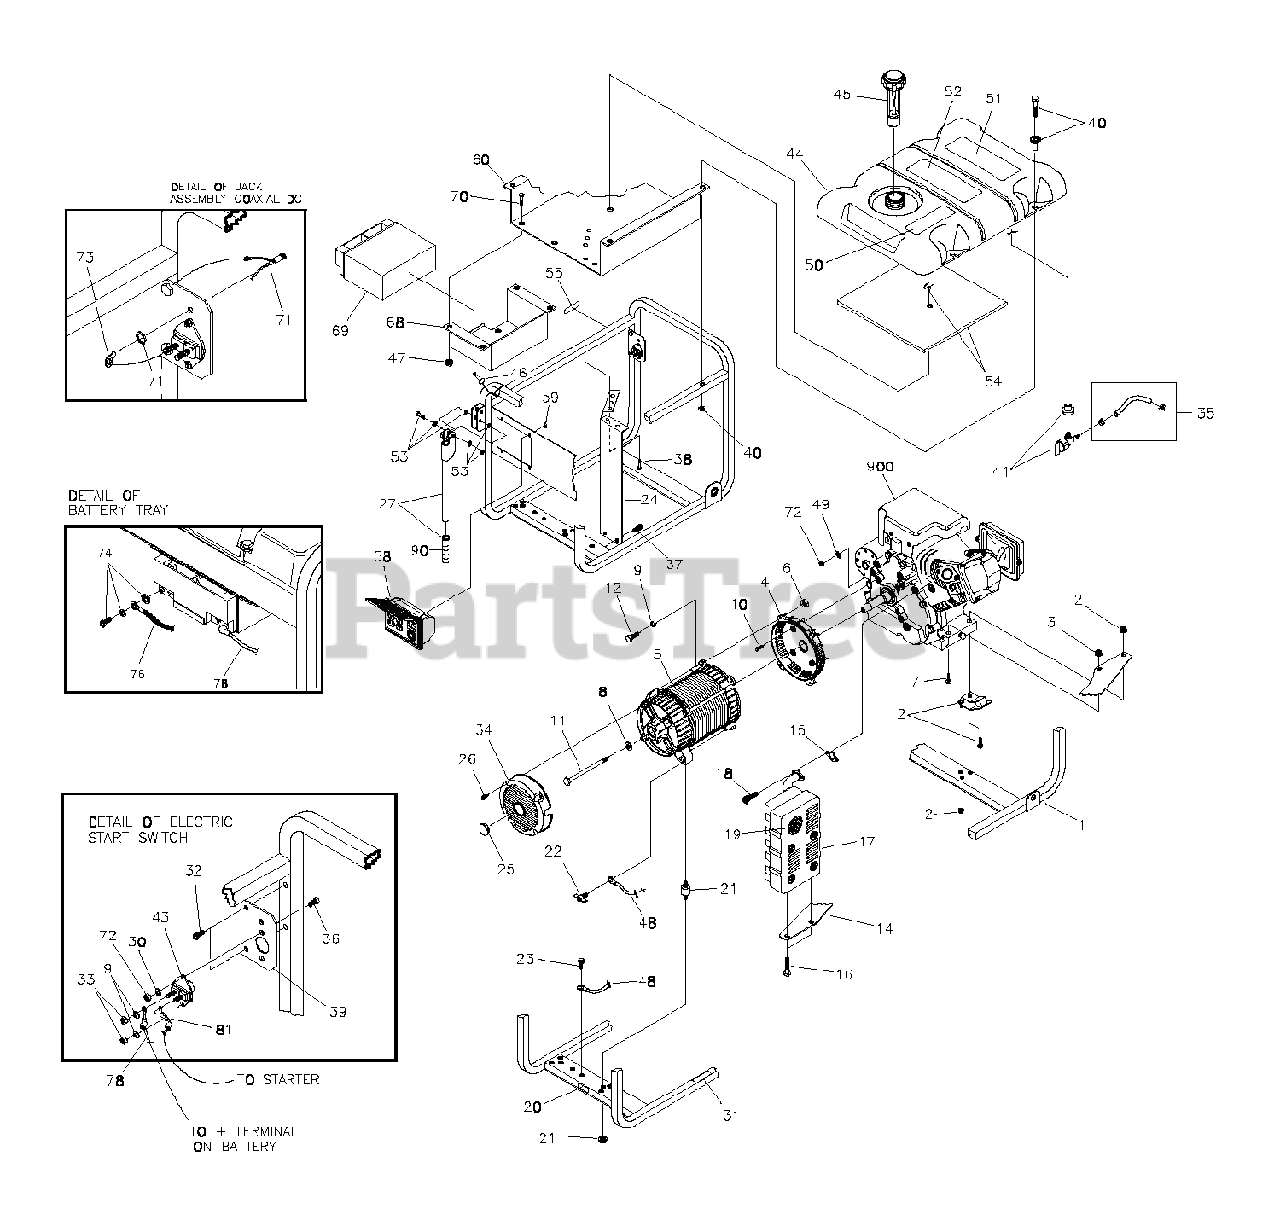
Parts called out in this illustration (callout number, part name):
1	CRADLE
2	KIT, Vibration Mount, 45°
3	NUT, M8 Flange Serrated
4	HOUSING, Engine Adapter
5	ALTERNATOR ASSEMBLY
7	TPHMS, M8 - 1.25 x 35
8	WASHER, Flat M8.4 x 22.2 x 3
10	SBHCS, 3/8-16 x 7/8 Lg.
11	HHCS,5/16-24 x 7-7/16
14	BRACKET, Muffler
15	GASKET, Exhaust
19	SCREEN, Spark Arrest
20	DECAL, Ground, Green
21	KIT, Vibration, Mount
22	SCREW, Wing M6 - 1.0 x 16
23	SCREW, 10-16 x 3/4 Self Drill
24	SHIELD, Heat
26	SCREW, M5-0.8 x 10,Taptite
27	ASSY, Handle (Includes Item 79)
31	DECAL, Warning Exhaust
32	SCREW, 10 - 16 x .68 Self-Drill
34	COVER, Bearing Carrier with Cap
35	KIT-FUEL, Hose (Cut To Fit)
37	HHCS, 12 - 14 x 7/8" Self Driller
38	SCREW, 10-24 x 1/2 Crimptite
39	BRACKET, Switch
40	KIT, Hardware Tank Fuel (Includes Qty. of 4)
41	KIT, Valve, Fuel Tank
43	SWITCH, Starter
44	ASSY, Tank, Fuel (Includes Items 41, 50, 51 & 52)
45	CAP, Fuel Gauge
46	PIN, with Lanyard
47	NUT, M6 Flange Lock
48	WIRE, Ground
49	* WASHER, M6 Shakeproof
50	DECAL, Instruction, Fuel Level
51	DECAL, Danger
52	DECAL, Operating Instructions
53	KIT, Fold Down Handle Hardware
54	KIT, Insulation with Clip
55	DECAL, Fuel Shut Off
58	ASSY, Control Panel (see Control Panel page)
60	SHIELD, Heat
68	TRAY, Battery
71	ASSY, Jack, DC
73	LUG, 5/16 #22/18 I-S
74	KIT, Battery Hardware
76	ASSY, Wire, #55
78	ASSY, Wire, #13
81	ASSY, Wire, #16
90	GRIP, Handle
900	ENGINE, Briggs & Stratton
